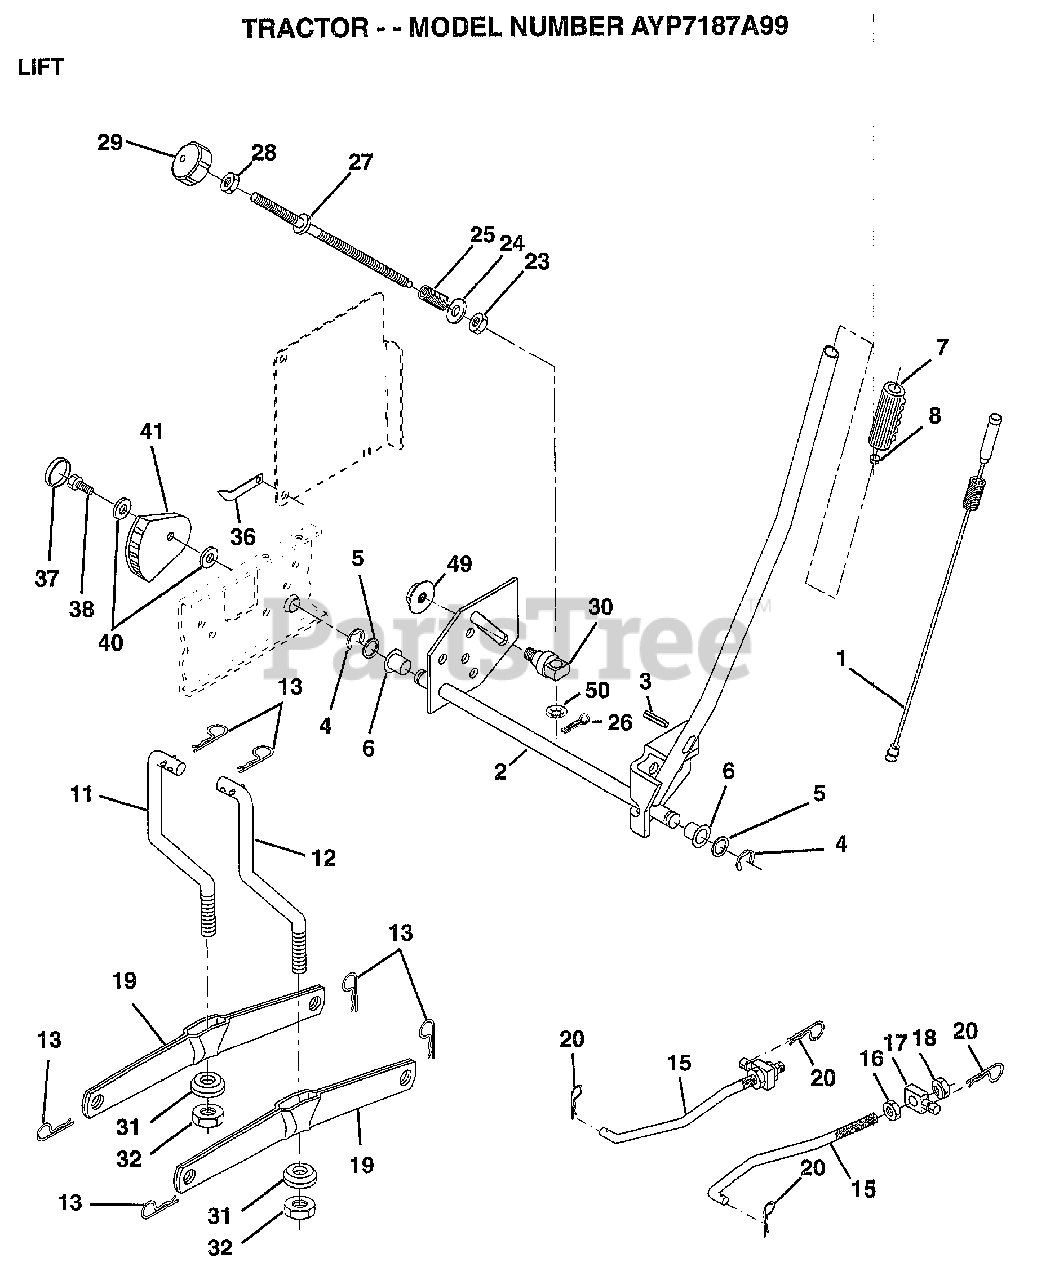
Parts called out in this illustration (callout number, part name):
1	WIRE ASM W.SPRING
2	"SHAFT ASM LIFT,RH"
3	PIN-GROOVE LT
5	WASHER
6	NYLON BEARING
7	GRIP HANDLE
15	LINK.FRONT
16	NUT
17	TRUNION
18	NUT.LK.W/WSH.1/2.
19	ARM SUSP REAR
20	RETAINER SPRING
23	NUT T
24	WASHER
25	SPRING T
28	NUT
29	KNOB INF 3/8-16
30	TRUNNION
31	BEARING PVT LH
32	NUT.CROWNLOCK.3/8
36	POINTER-INDICAT
37	"PLUG,HOLE"
38	SCREW
40	WASHER
41	INDICATOR HEIGHT
49	NUT.HXFLG.LOCK.
50	NUT PUSH M
